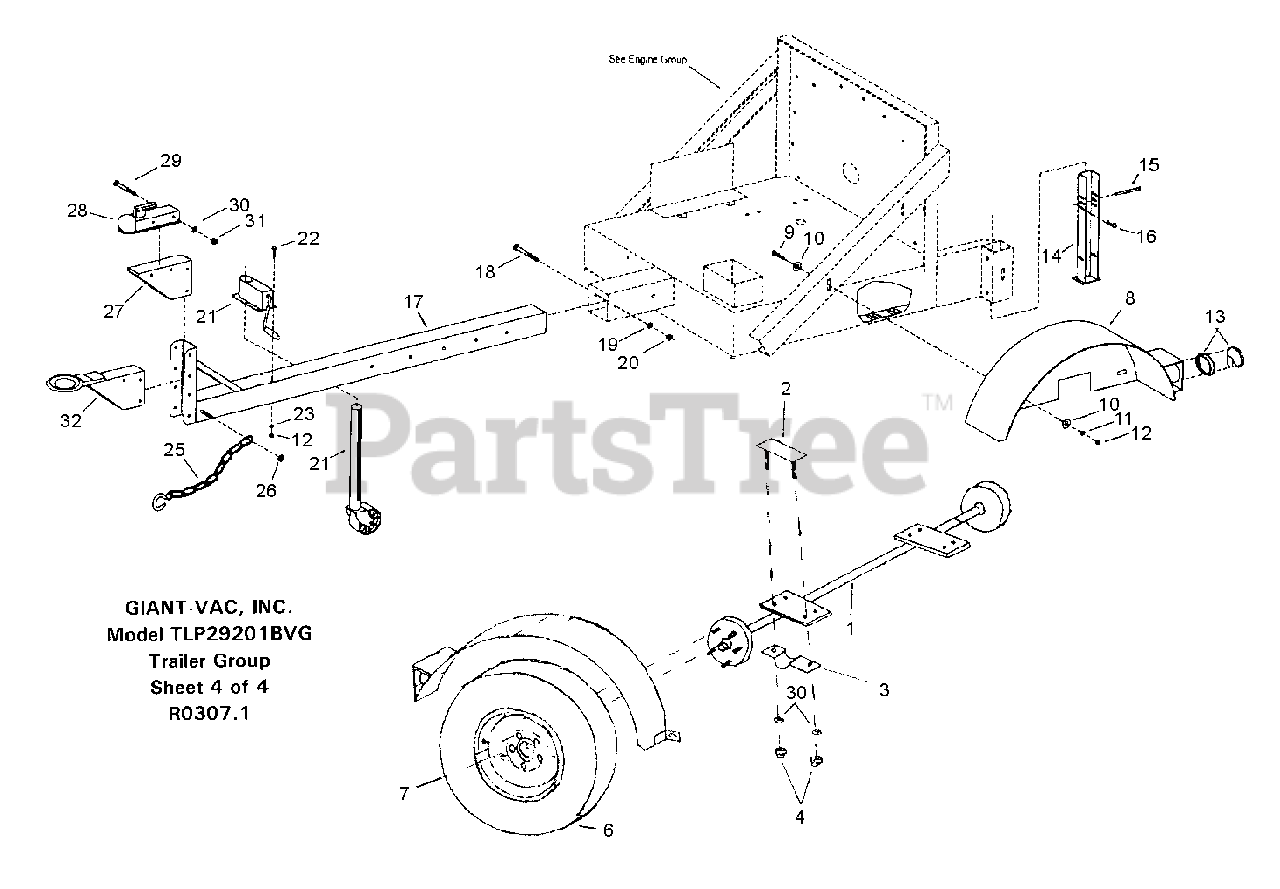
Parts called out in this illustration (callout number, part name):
1	Axle 2,000 lbs
2	Axle Bolt Plate
3	Axle Reinforcement Plate
4	1/2 Nylon Lock Nut
6	F78 x 15 Tire and Wheel Assembly
7	1/2-20 Lug Nut
8	Fender - Left Side
9	3/8-16 x 1" Hex Bolt
10	3/8 Flat Washer
11	3/8 Lock Washer
12	3/8-16 Hex Nut
13	Tail Lamp (w/Rubber Mounting Ring)
14	Support Leg
15	3/8 x 4" Clevis Pin
16	Bridge Pin
17	Draw Bar - Swing Jack Style
18	5/8 x 4-1/2" Hex Bolt
19	5/8 Split Lock Washer
20	5/8 Lock Nut
21	Jack, Trailer Support Swing Away Style
22	3/8-16 x 5" Hex Bolt
23	3/8 Split Lock Washer
25	Chain, Safety w/1 S-Hook
26	1/2-13 x 5" Hex Bolt
27	Ball Hitch Mount, Black
28	Ball Hitch
29	1/2-13 x 3-1/2" Hex Bolt
30	1/2 Lock Washer
31	1/2-13 Lock Nut
32	Pintle Ring (Optional)
36	Chain, Nozzle Retainer 1/2 x 12"
